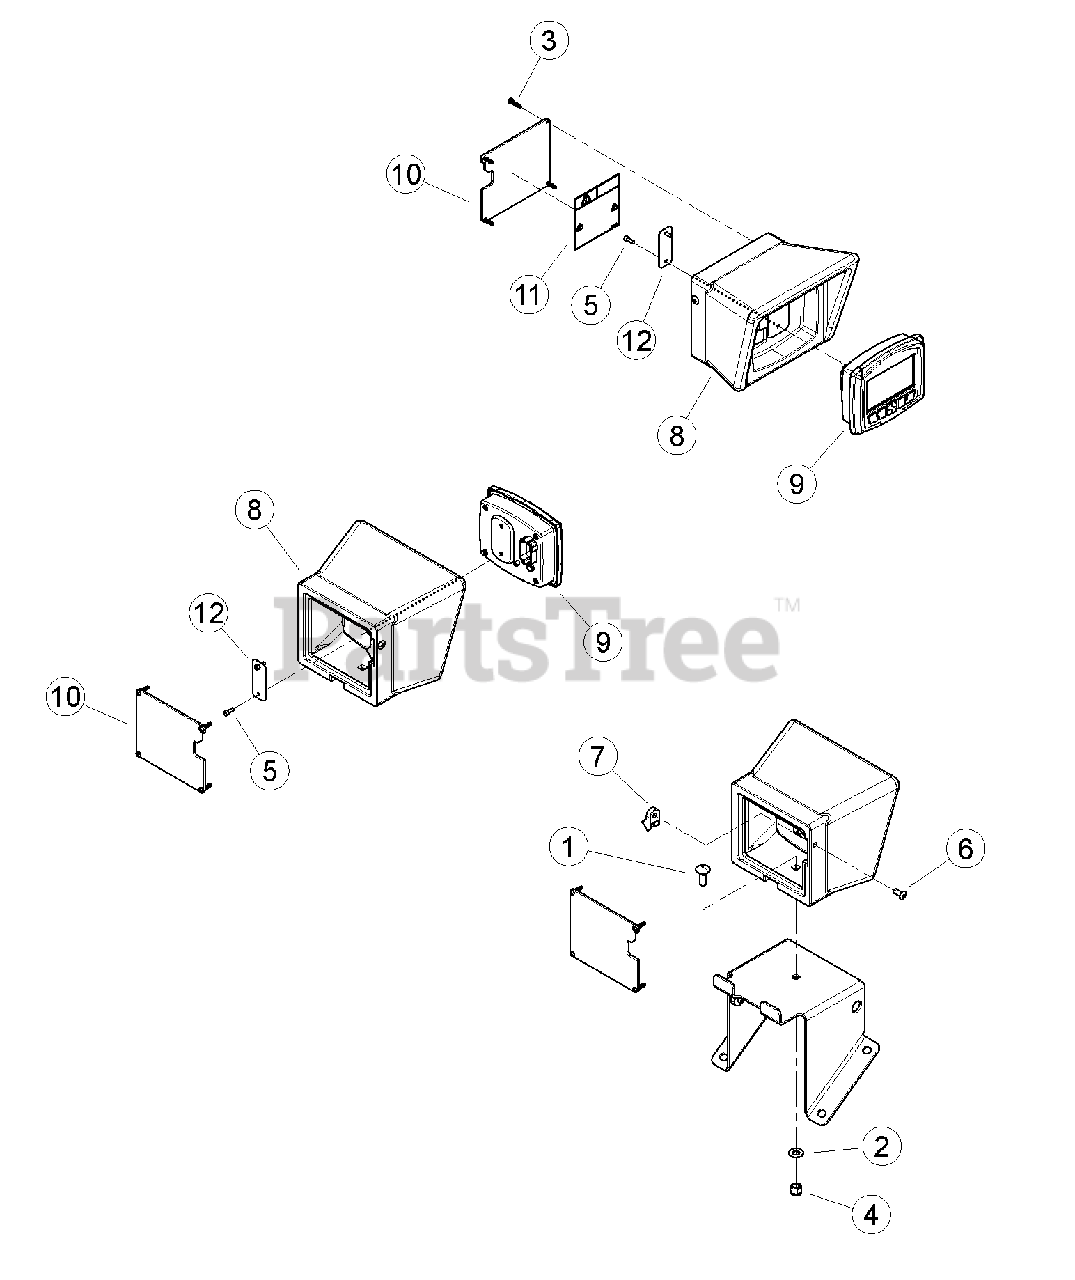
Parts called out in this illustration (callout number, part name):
1	BOLT, 3/8 X 1" GR5 CRG NC ZP
2	WASHER, 3/8" SAE FLAT ZP
3	SCREW, 10-16 3/4 LONG FOR PLASTIC
4	NUT, 3/8" NE NYLOCK ZP
5	SCREW, #8-32 X 1/2 SKT HD CAP
6	RIVET, AL BLIND 1/4 X 3/4 DOME HEAD
7	CLAMP, CABLE MOUNT
8	ENCLOSURE, CONTROLLER
9	CONTROLLER, CL-709-100 MASTER
10	ASSEMBLY, ENCLOSURE COVER WITH DECAL
11	DECAL, DDC MOUNTING INFO
12	PLATE, DDC WASHER
